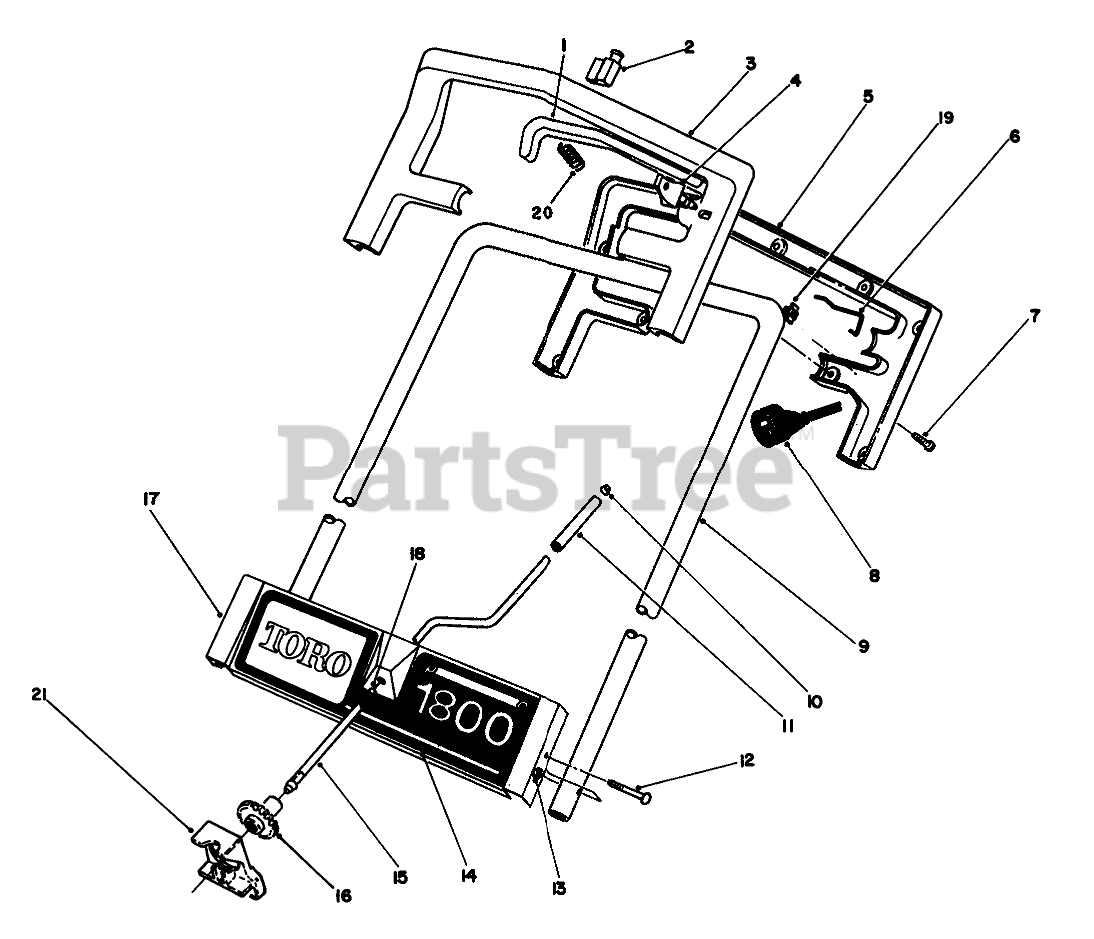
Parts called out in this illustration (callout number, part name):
1	Bar-Switch
2	SWITCH
3	1800 U. CNTRL HANDLE
4	KEY - 1800
5	1800 L CNTRL HANDLE
6	SPRING, INTERLOCK
7	Screw
8	POWER SUPPLY CORD
9	Tube-Handle, Upper
10	PUSHNUT-CAP, WASHER
11	Sleeve-Crank, Chute
12	Screw-HH
13	NUT-LOCK, NI
14	DECAL - ESCUTCHEON
15	Rod-Crank, Chute
16	Gear-Crank, Chute
17	Plate-Escutcheon
18	Bushing-Nyliner
19	LOCK SLIDER
20	Spring
21	Brake-Gear
